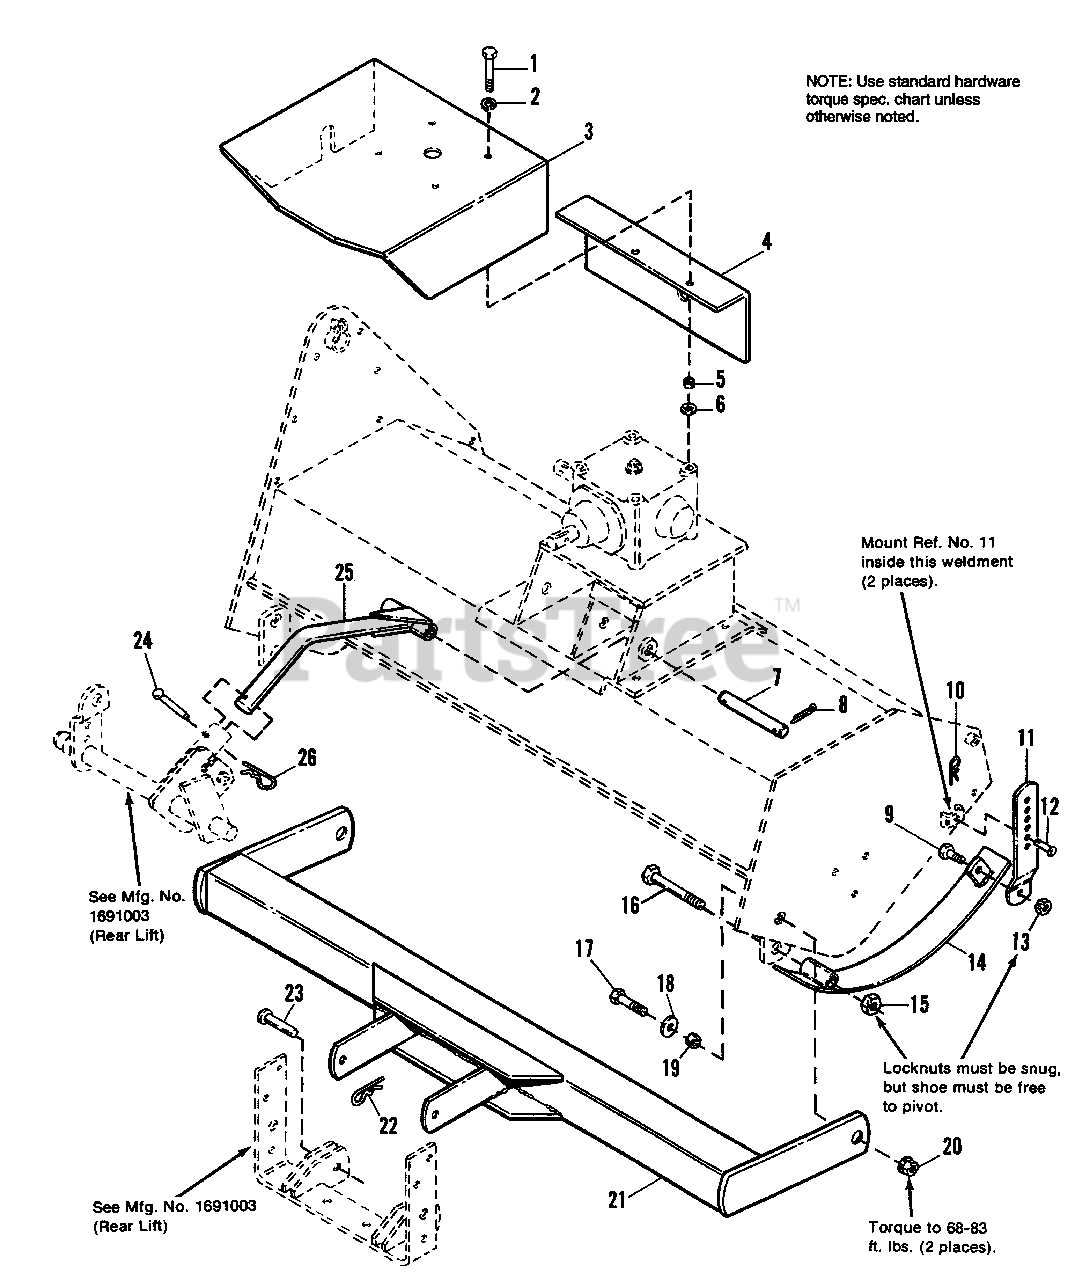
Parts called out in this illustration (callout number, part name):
1	CAPSCREW, Hex Hd., 3/8-16 x 1-3/4
2	WASHER, Lock Spring
3	SHIELD, Gear Box, Top
4	SHIELD, Gear Box, Back
6	NUT, Push Pal, 1-3/8
7	PIN, Pivot
8	PIN, Cotter
9	CAPSCREW, Hex Hd., 3/8-16 x 1
10	PIN, Quick, 1-7/8
11	BRACKET, Adjusting
12	PIN, Yoke, 3/8
13	LOCKNUT, Hex, 3/8-16
14	SKID ASSY.
15	LOCKNUT, Hex, 5/8-11
16	CAPSCREW, Hex Hd., 5/8-11 x 3
17	CAPSCREW, Hex Hd., 1/2-13 x 1-1/2
18	WASHER, Plain, 1/2 x 1-1/4
20	NUT, Lock Flange, 1/2-13
21	HITCH ASSY., 38" Tiller
22	CLIP, Spring
23	PIN, Yoke
24	PIN
25	LIFT BAR ASSY.
26	CLIP, Hair Pin, 3/32 x 1-5/8
